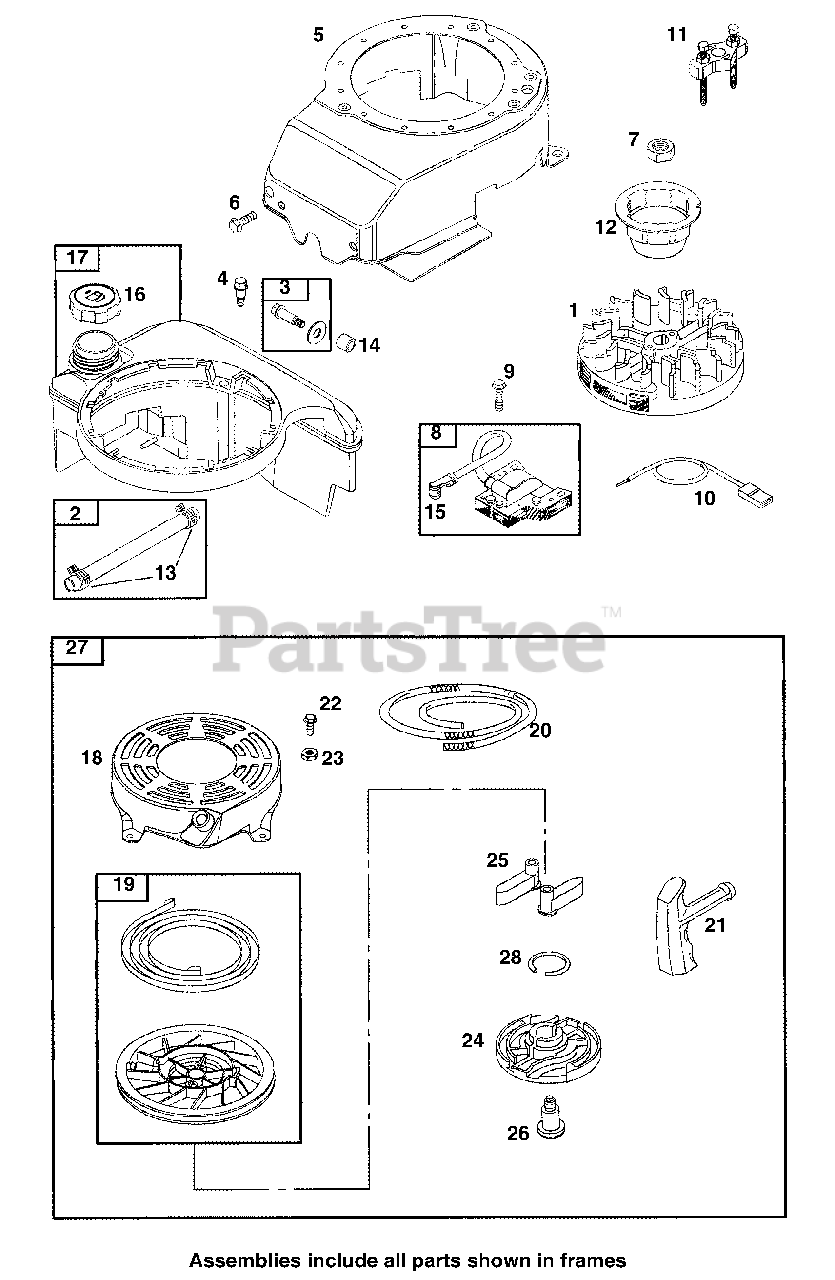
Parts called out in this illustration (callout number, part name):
1	Flywheel
2	Fuel Line
3	Washer Kit Screw
4	Shoulder Screw
5	Blower Housing
6	Hex Screw
7	Flywheel Nut
8	Magneto Armature
9	Hex Screw
10	Stop Wire
11	Flywheel Puller
12	Flywheel Cup
13	Hose Clamp
14	Fuel Tank Spacer
15	Cable Terminal
16	Fuel Tank Cap
17	Fuel Tank
18	Rewind Starter Housing
19	Starter Pulley
20	Starter Rope (Cut to 88-5/8")
21	Starter Rope Grip
22	Hex Screw
23	Hex Nut
24	Pawl Friction Plate
25	Rachet Pawl
26	Shoulder Screw
27	Rewind Starter
28	Friction Spring
